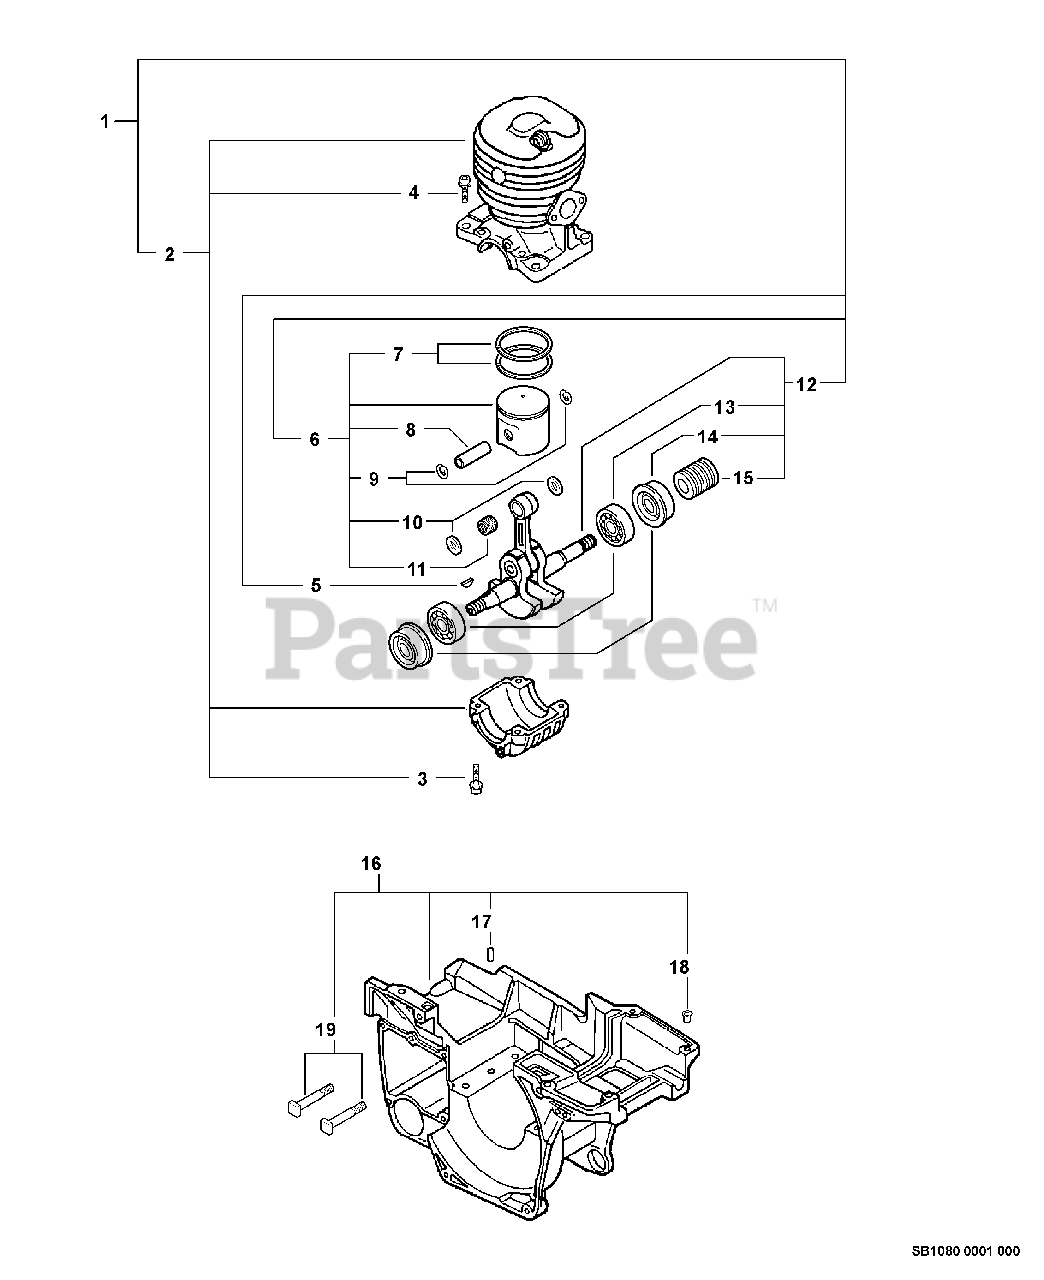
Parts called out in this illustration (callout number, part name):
1	SHORT BLOCK -- SB1080
2	CRANKCASE KIT
3	SCREW - 5X20
4	SCREW - 5X22
6	PISTON KIT
7	RING, PISTON
8	PIN, PISTON
9	RING, RETAINING
10	SPACER, PISTON
11	BEARING, NEEDLE
12	CRANKSHAFT ASSY
13	BEARING, BALL - 6202
14	SEAL, OIL
15	GEAR - WORM
16	ENGINE COVER ASSY
17	PIN - LOCATING
19	STUD, GUIDE BAR
